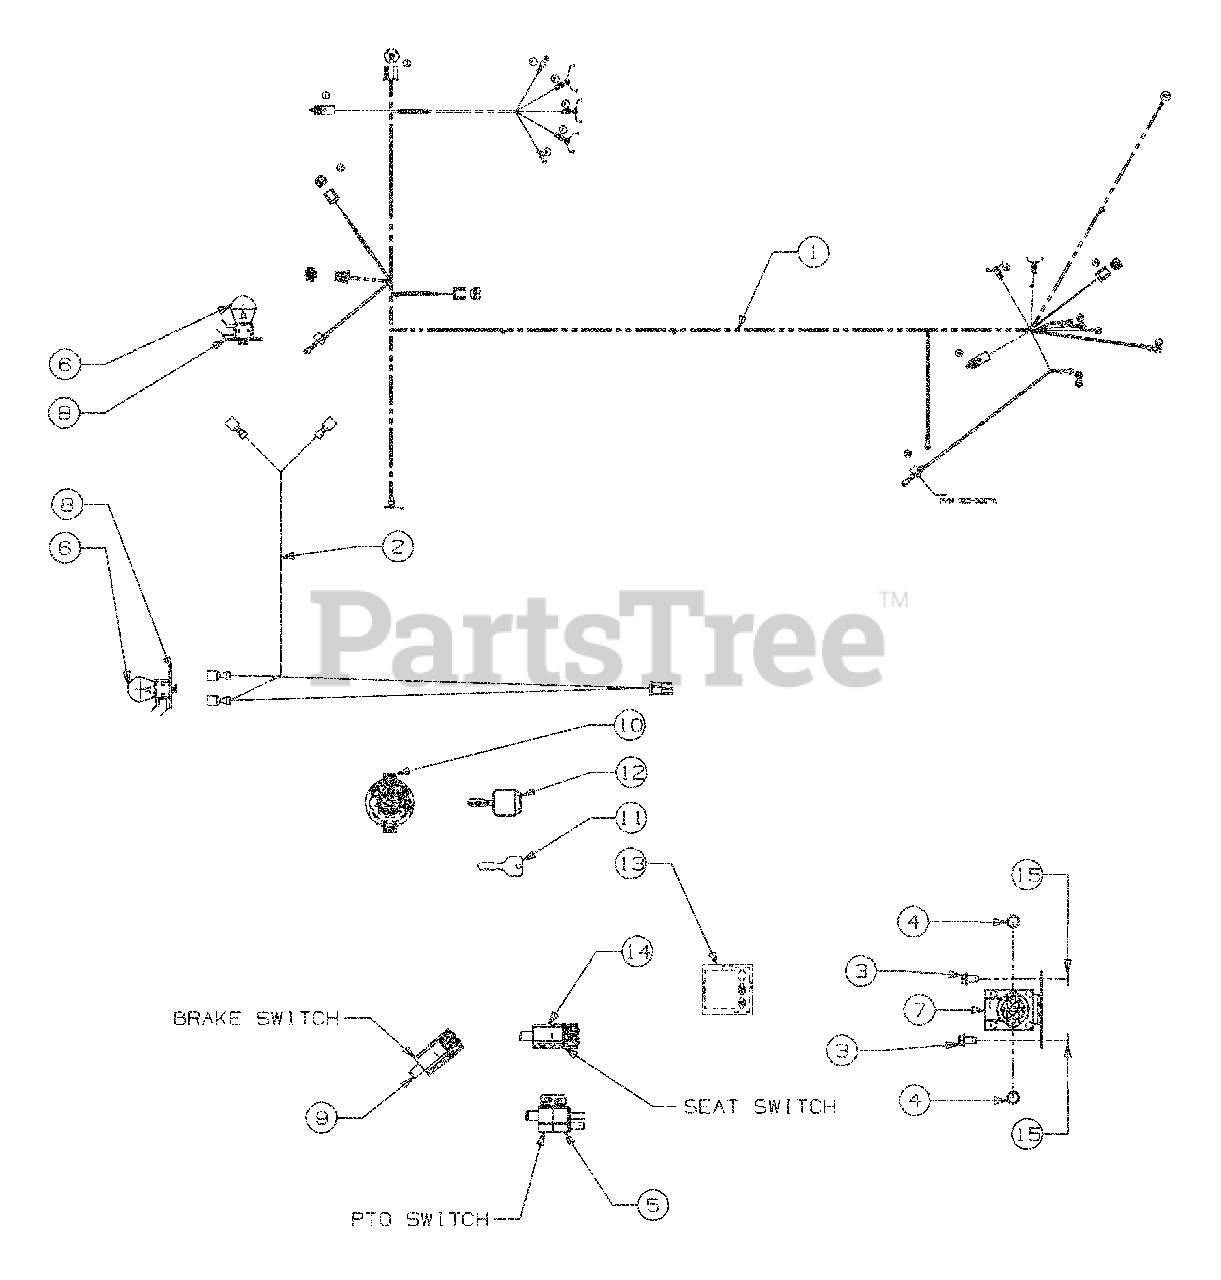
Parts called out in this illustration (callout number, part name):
1	HARN ASM:500:MANPTO W/MON
2	HARN ASM:UNIVERSAL:HEADLIGHT
3	SCR:TT:1/4-20:0.500:HXINDWSH
4	NUT:HEX:1/4-20:SEMS
5	SW:DELTA:NO/NC/NC SNAP MT
6	MINIATURE LAMP 12V SOCKET TYPE
7	SOL:12V:100 AMP
8	SOC:LAM:NYLON 1/4 TURN
9	SW:INTLK:NO/NC SNAP MT
10	SW:KEY:4 POS DELTA
11	KEY:SW:DELTA
12	KEY:DELTA PLASTIC
13	IND:MONITOR:W/AMMETER
14	SW:INTLK:NO/NO SNAP MT
15	EXTERN L-WASH 1/4
